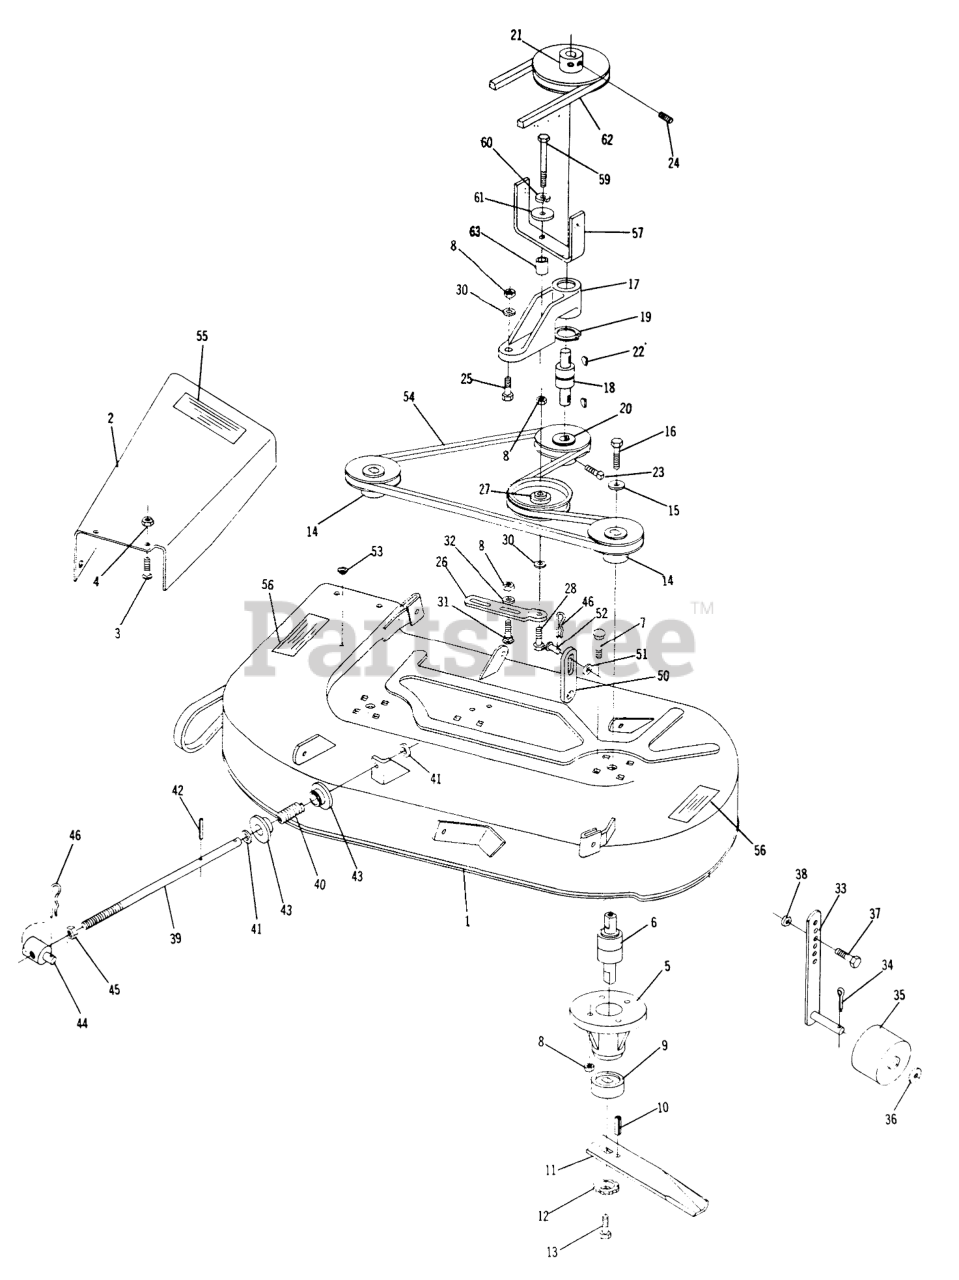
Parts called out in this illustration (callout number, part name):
2	Extension-Chute
3	Bolt 5/16-18 x 5/8*
4	Nut-Nylok
7	Bolt-Carriage 3/8-16 x 1
10	SPIROL ROLL PIN
13	Bolt 3/8-16 x 7/8
14	PULLEY
15	WASHER
16	Bolt 3/8-16 x 3/4 Hex
20	PULLEY-LOWER DRIVE
22	KEY-WOODRUFF
23	Set Screw-5/16-18 x 3/8
24	Set Screw
25	Bolt 3/8-16 x 1
28	Bolt, 3/8 16 x 2
30	Washer
31	Bolt 3/8-16 x 1
32	Washer-3/8 U.S.
34	Cotter Pin
35	ROLLER ASSY
36	Washer
37	Bolt 5/16-18 x 1
38	Nut 5/16-18
41	Washer
42	PIN-ROLL
43	BUSHING
45	Jam Nut-7/16-14
46	Hairpin
50	LIFT LINK
51	WASHER-NYLON
52	Clevis Pin 3/8 x 3/4
53	Plug Button
59	Bolt, 3/8-16 x 1/2
60	Lockwasher
61	WASHER
